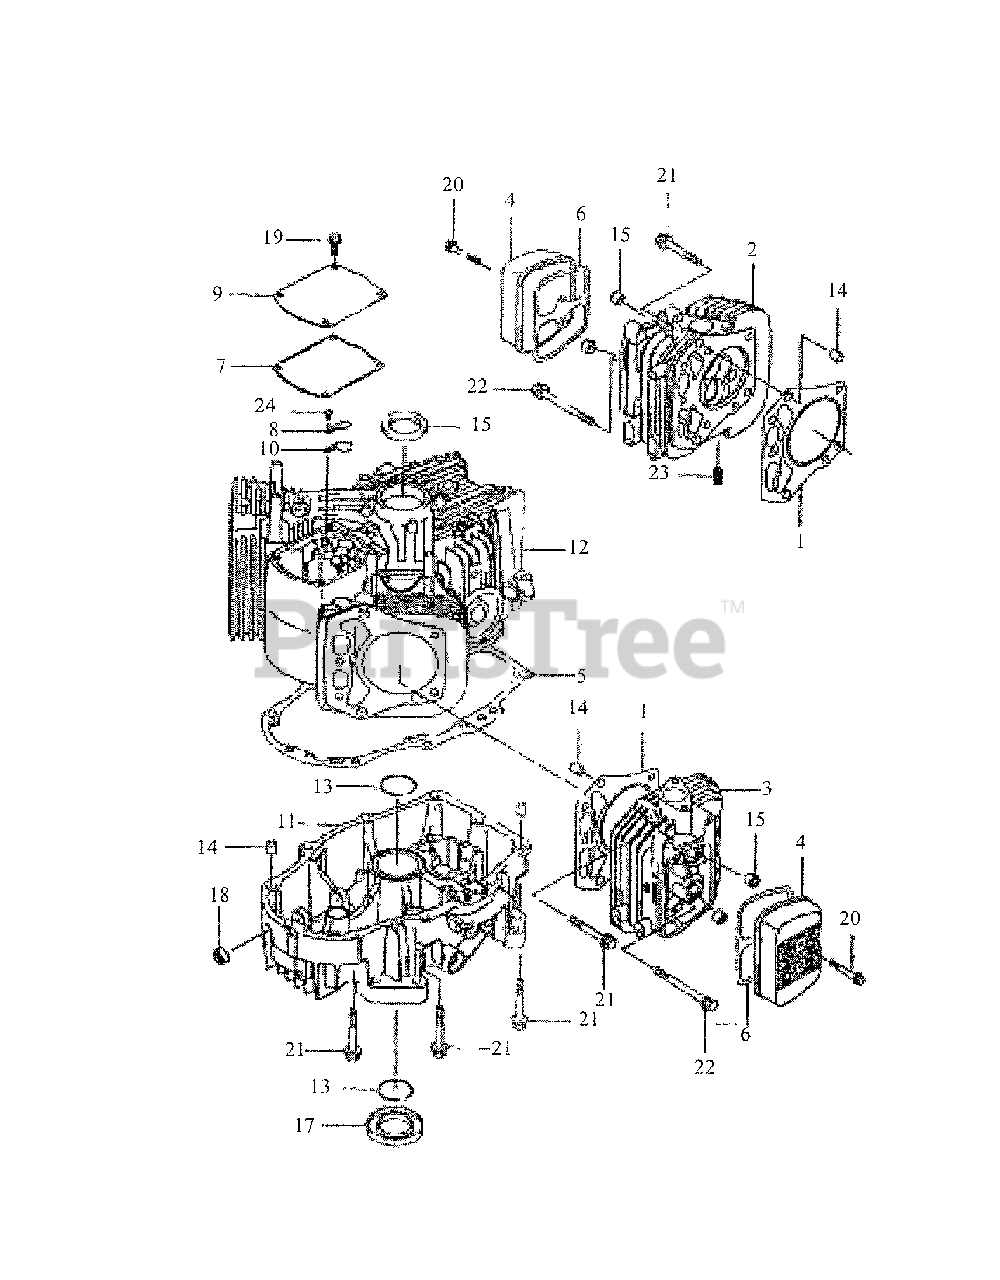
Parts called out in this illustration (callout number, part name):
1	Gasket-Head
2	Head-Cylinder # 1
3	Head-Cylinder # 2
4	Case-Rocker
5	Gasket, Crankcase
6	Gasket-Rocker Cover
7	Gasket-Breather
11	Cover-Crankcase
15	Seal-Oil - Valve Stem
17	Seal-Oil
18	Seal-Oil
19	Bolt-Flange
20	Bolt-Flange
21	Bolt-Flange
22	Bolt-Flange
23	Bolt-Stud
24	Screw-Pan
